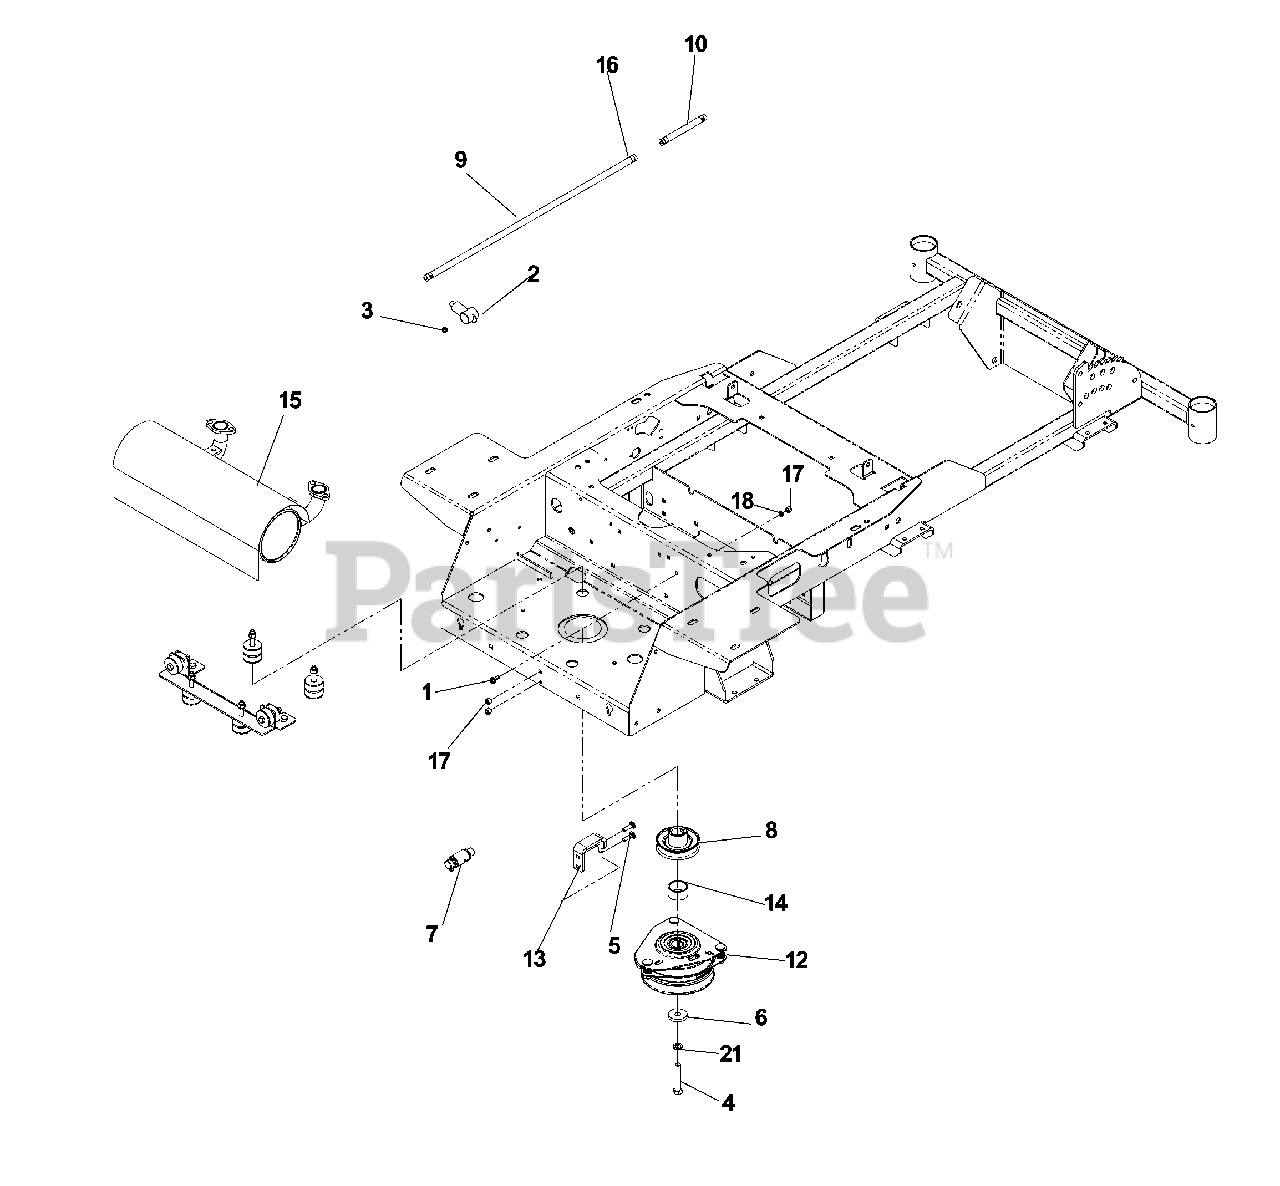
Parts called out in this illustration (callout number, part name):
1	SCREW- 1/4-20 X 5/8
2	INSULATOR
3	JAM NUT 1/4C
4	HEX SCREW 7/16-20 X 3
5	RHSNB, 1/4-20 X 1, GR5
6	CLUTCH, WASHER
7	OIL DRAIN FITTING
8	PULLEY, ENGINE
9	FUEL LINE 24"
10	FUEL LINE 5"
11	WASHER 7/16 LOCK
12	CLUTCH, OGURA - 90 FT/LB
13	TIE DOWN, CLUTCH
14	SPACER, ENGINE - PULLEY
15	MUFFLER
16	HOSE CLAMP
17	NUT 1/4-20 NYLOC
18	WASHER 1/4 INT TOOTH
